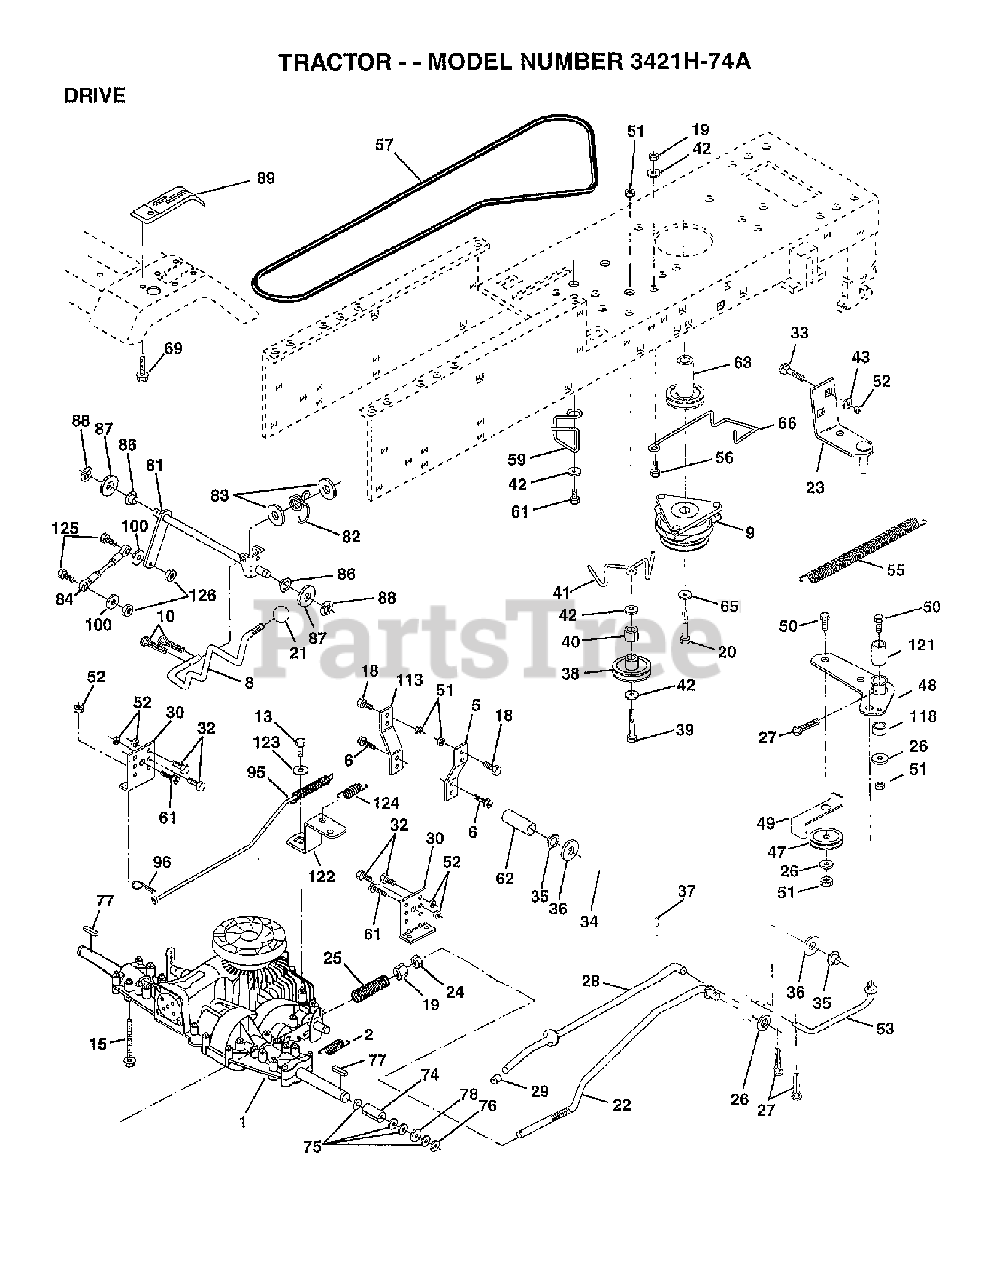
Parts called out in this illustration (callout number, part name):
1	Poulan TBD
2	SPRING T
5	STRAP TORQUE
6	Screw, Lt
8	ROD SHIFT
10	PIN COTTER
15	BOLT HEX 5/16-18 GR 5
19	NUT
20	BOLT
21	KNOB T (1/2-HOLE)
22	ROD BRAKE
23	BRACKET ASM MTG
24	NUT
25	SPRING ROD LT
27	COTTER PIN
29	PLUNGER CAP
30	BRACKET TRANSAXLE
32	BOLT
33	BOLT
34	SHAFT, FOOT PEDAL
35	BEARING.NYLON
36	WASHER LT
37	Drive Pin, 3/16 X 1"
38	FLAT IDLER PULLEY
40	SPACER T
42	WASHER
43	WASHER T
47	Idler Pulley
48	BELLCRANK ASSEMBLY
49	RETAIN BELT
50	Hex Bolt
51	LOCKNUT
52	LOCKNUT
55	SPRING, RETURN LT
57	Belt
62	PEDAL COVER
63	PULLEY CLU ELEC
65	LOCKWASHER
66	KEEPER BELT ENGINE
69	SCREW.HI-LO.CONSOLE
74	SPACER, AXLE PVST
76	E-RING LT
77	SQUARE KEY
81	SHAFT ASM CROSS HYDRO
82	SPRING,TORSION
83	WASHER
84	ROD, TIE PVST 20"
86	BUSHING.STEERING.ROD
87	WASHER D
88	KLIP RING
95	ROD ASM BYPASS PVST
96	RETAINER M
100	WASHER M
113	STRAP TORQUE LH LT
121	NYLINER CLUTCHING
122	PLATE BYPASS PVST
124	RETURN SPRING
125	BOLT.FIN.HEX.5/16-18UNC X 1.00
126	Lock Nut
